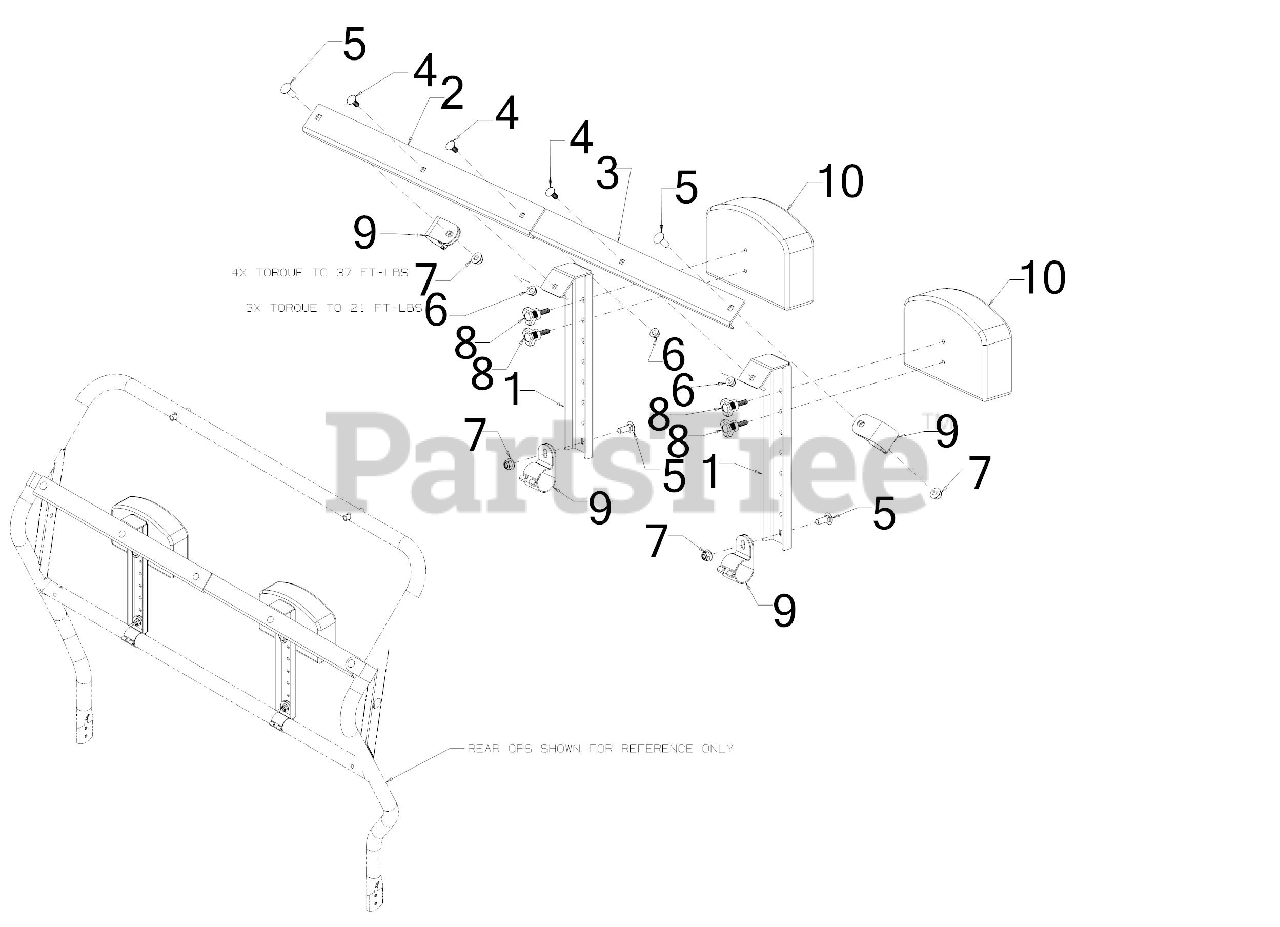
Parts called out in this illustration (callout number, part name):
1	HEADREST MOUNTING BRACKET
2	HEADREST MOUNTING BRACKET (LH)
3	HEADREST MOUNTING BRACKET (RH)
4	CARRIAGE BOLT 5/16-18 x .75
5	CARRIAGE BOLT 3/8-16 x 1.00 GR5
6	FLANGE LOCK NUT 5/16-18
8	KNOB ASSEMBLY 5/16-18
10	HEADREST PAD
